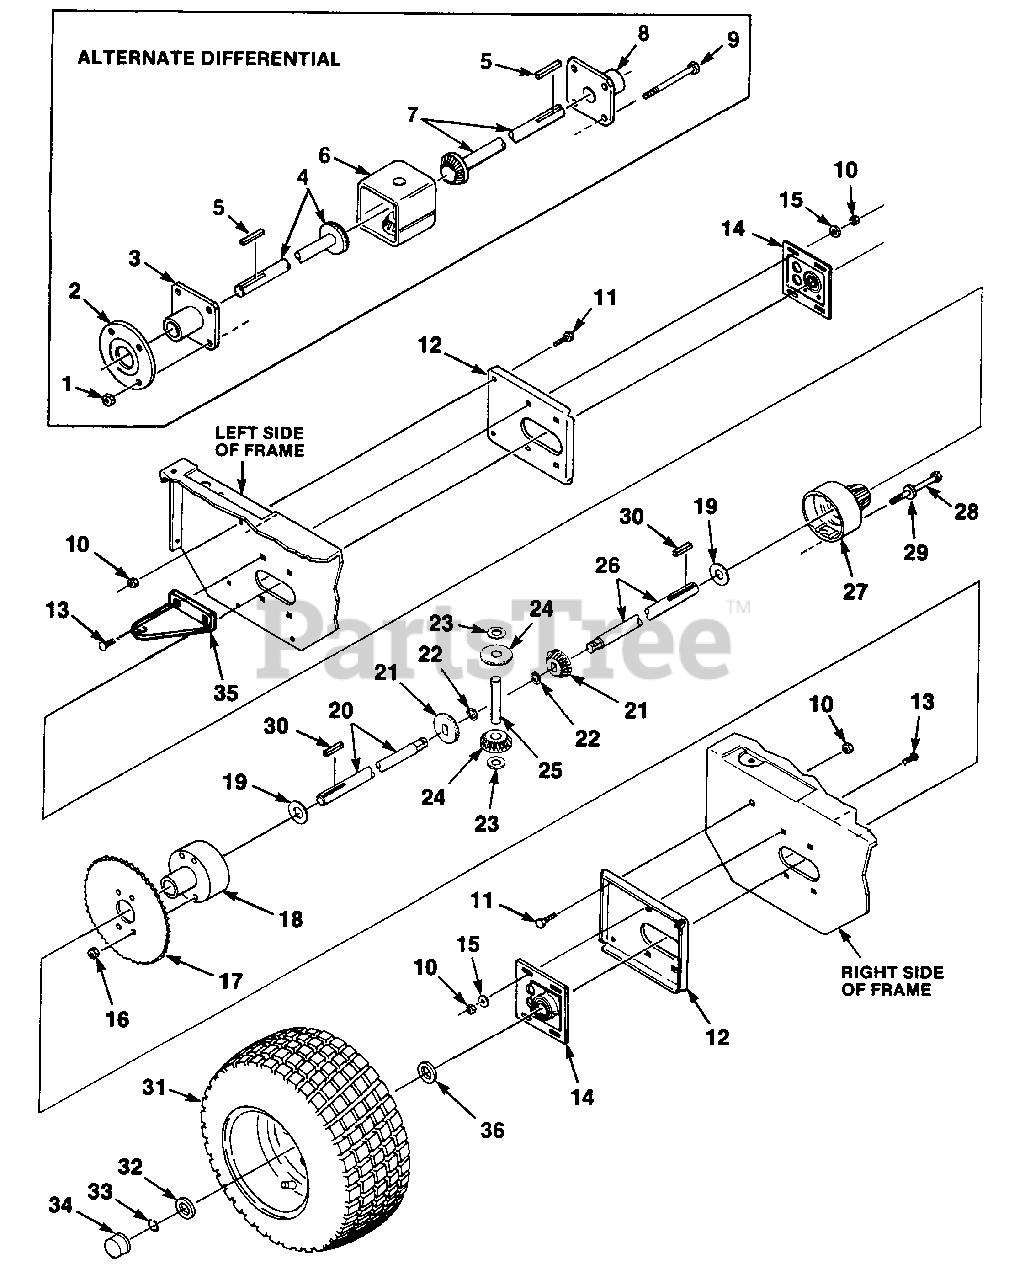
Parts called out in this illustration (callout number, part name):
2	SPACER- Differential
3	CAP & BEARING (R.H.)
4	AXLE- R.H. W/Gear
5	KEY
6	HOUSING & GEAR
7	AXLE- LH W/Gear
8	CAP & BEARING (L. H.)
9	SCREW- Hex 5/16-18 x 4
10	NUT- 1/4-20 lock
11	SCREW- 1/4-20 x 5/8
12	SUPPORT- Frame
13	BOLT- 1/4 x 3/4
14	RETAINER & BEARING
15	WASHER
16	NUT- Centerlock 3/8-16
17	SPROCKET- 48 tooth
18	HOUSING- L.H. Gear
20	AXLE- Short
21	GEAR- Bevel
22	RING- Snap
23	WASHER- Thrust
24	GEAR- Pinion
25	PIN- Drive
26	AXLE-Long
27	GEARING HOUSING- R.H.
28	SCREW- Mach hex hd.
31	TIRE & HUB (rear)
32	SPACER- Axle
33	RING-Retaining
36	WASHER- Flat
